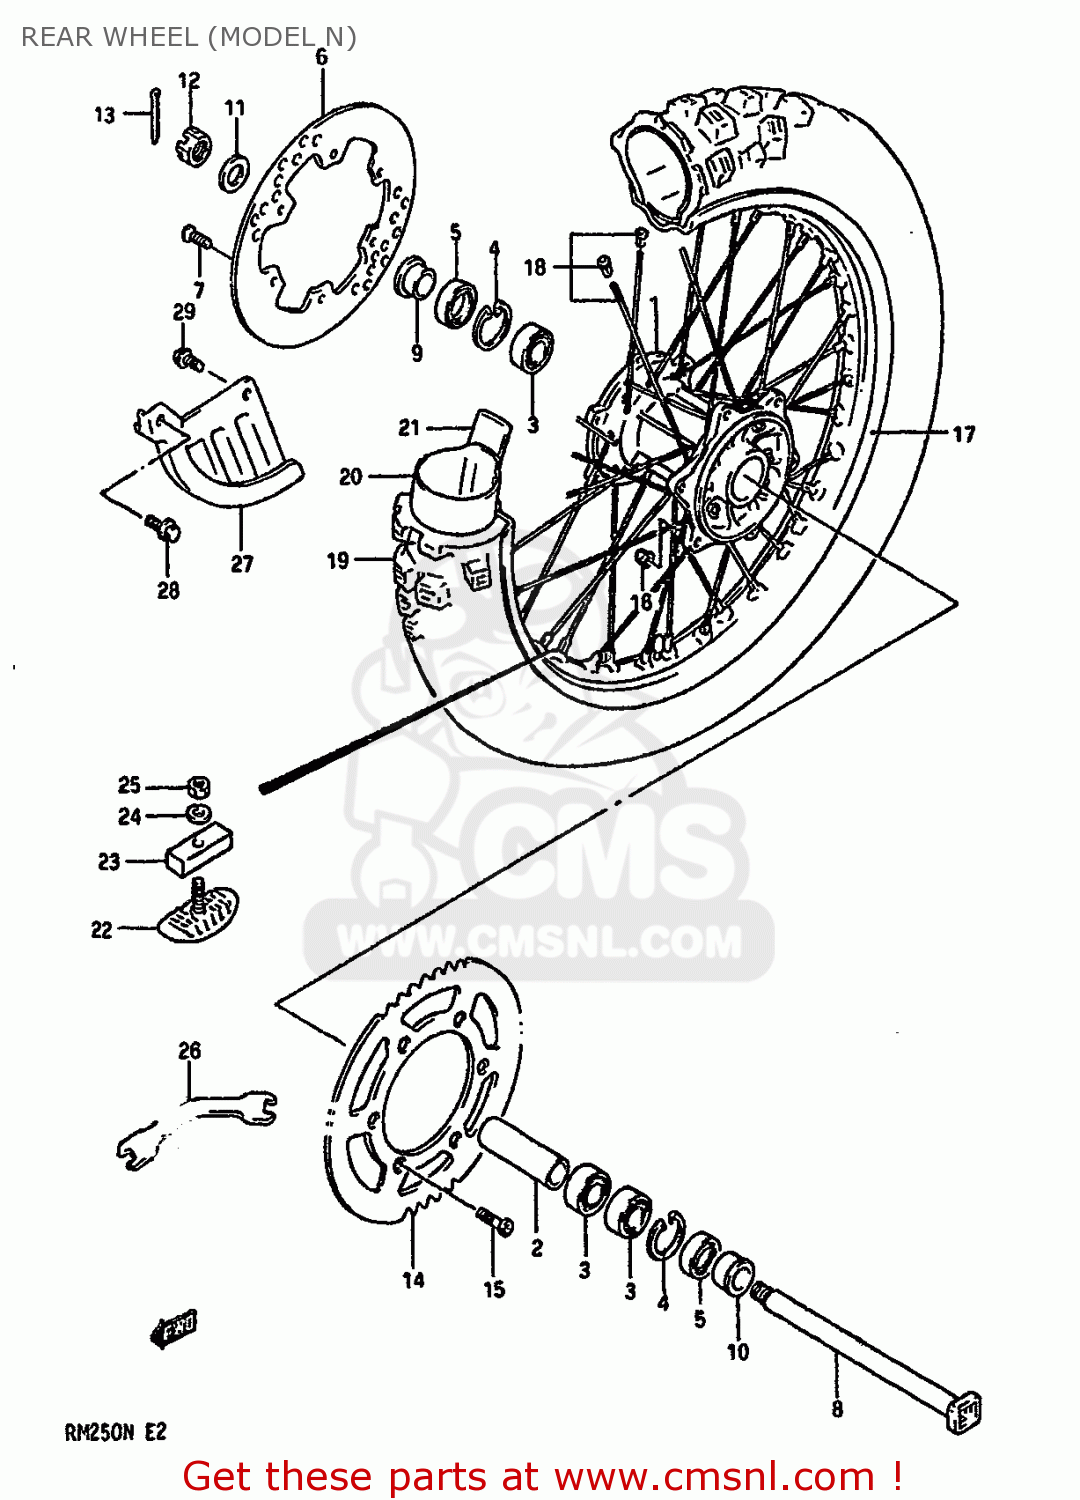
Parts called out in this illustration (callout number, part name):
1	HUB,RR WHEEL
2	SPACER,RR HUB BEARING
3	BEARING
4	CIRCLIP
5	SEAL,OIL(26X42X8)
6	DISC,RR BRAKE
7	SCREW
8	AXLE,RR
9	SPACER,RR AXLE,R
10	SPACER,REAR AXLE,LEFT
11	WASHER
12	NUT 18MM
13	PIN,COTTER
14	SPROCKET,REAR
15	BOLT(8X30.5)
16	NUT
17	RIM,RR WHEEL(2.15X19 AL)
18	SPOKE SET,RR WHEEL
19	TIRE
20	TUBE ASSY,WHEEL INNER
21	PROTECTOR
22	STOPPER,BEAD
23	CUSHION,BEAD STOPPER
24	WASHER
25	NUT
26	SPANNER,OPEN
27	COVER,REAR DISC
28	BOLT
29	BOLT
30	SPANNER,OPEN
